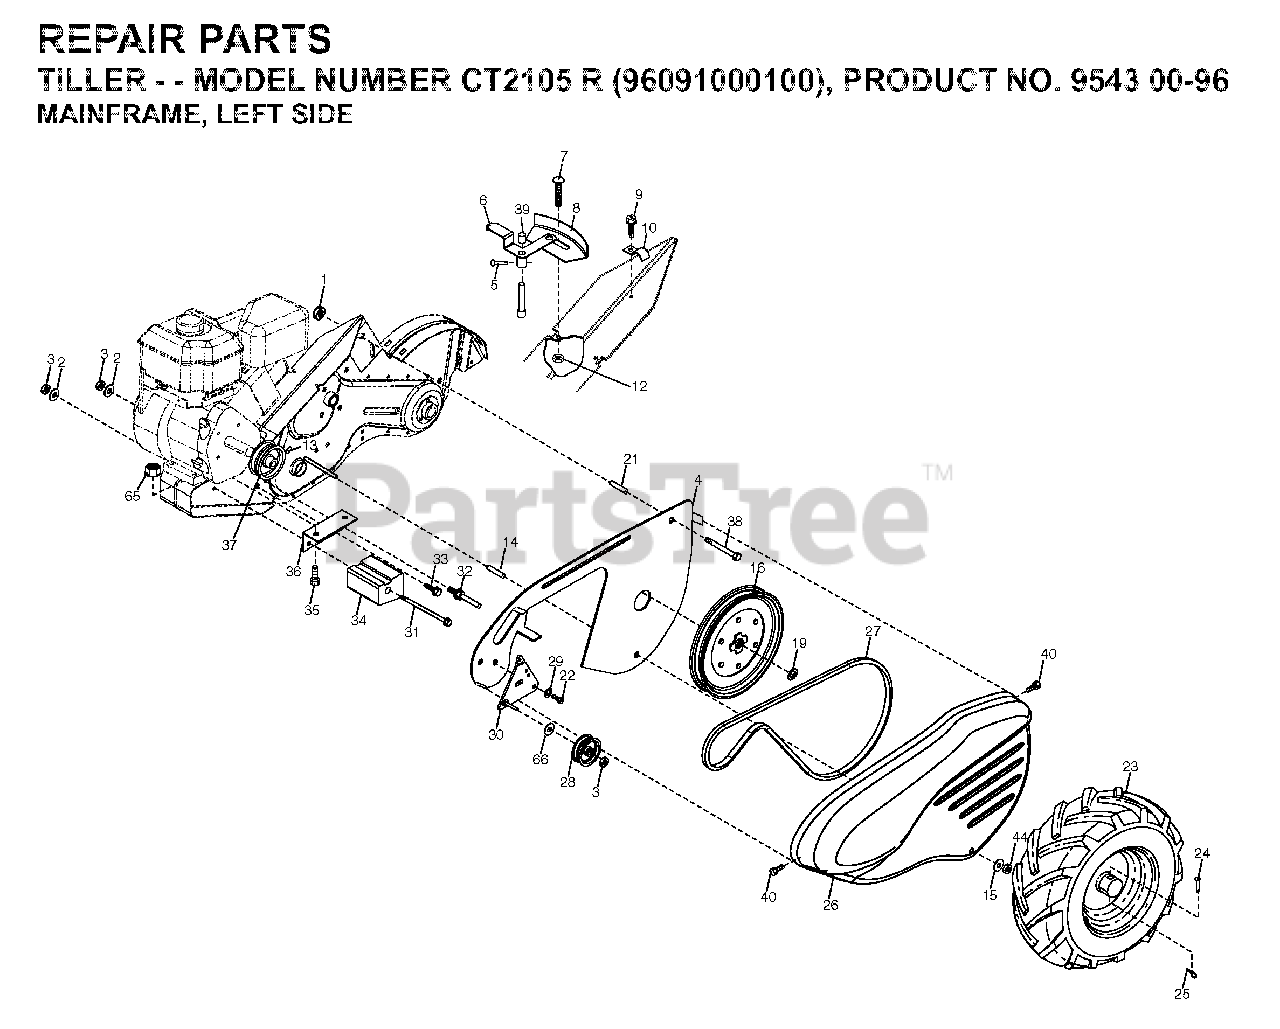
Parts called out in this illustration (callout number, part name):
1	NUT
2	WASHER, LOCK 3/8
3	NUT.HEX.3/8-16UNC
5	PIN.SPIROL.FLARED
6	LEVER ASM CRT
9	TAPPING SCREW
10	CONDUIT CLIP T
12	NUT
13	SET SCREW **
14	SPACER-SPLIT.327 X .42
15	WASHER
16	SHEAVE, TRANSMISSION
19	RETAINING RING LT
21	SPACER CRT
23	RIM
23	VALVE STEM LT
24	RIVET,DRILLED
25	RETAINER M
27	V-BELT
28	PULLEY-IDLER TI
29	KLIP RING
30	BRACKET.ASM.IDLER
31	BOLT.FIN.HEX.3/8-16UNC
32	SHIFT ARM CRT
33	BOLT
34	COUNTERWEIGHT.LH.CRT
35	BOLT, HEX 5/16-18X1-3/4
36	BRACKET LH CRT
37	ENGINE PULLEY
38	BOLT
39	CAP.PLUNGER.BLACK
40	SCREW.HEX.WSH.SLT.#10-24X.50
44	NUT.71038.31-18.HEX.NYLOCK
65	LOCKNUT-FLANGE 5/16-18
66	WASHER
